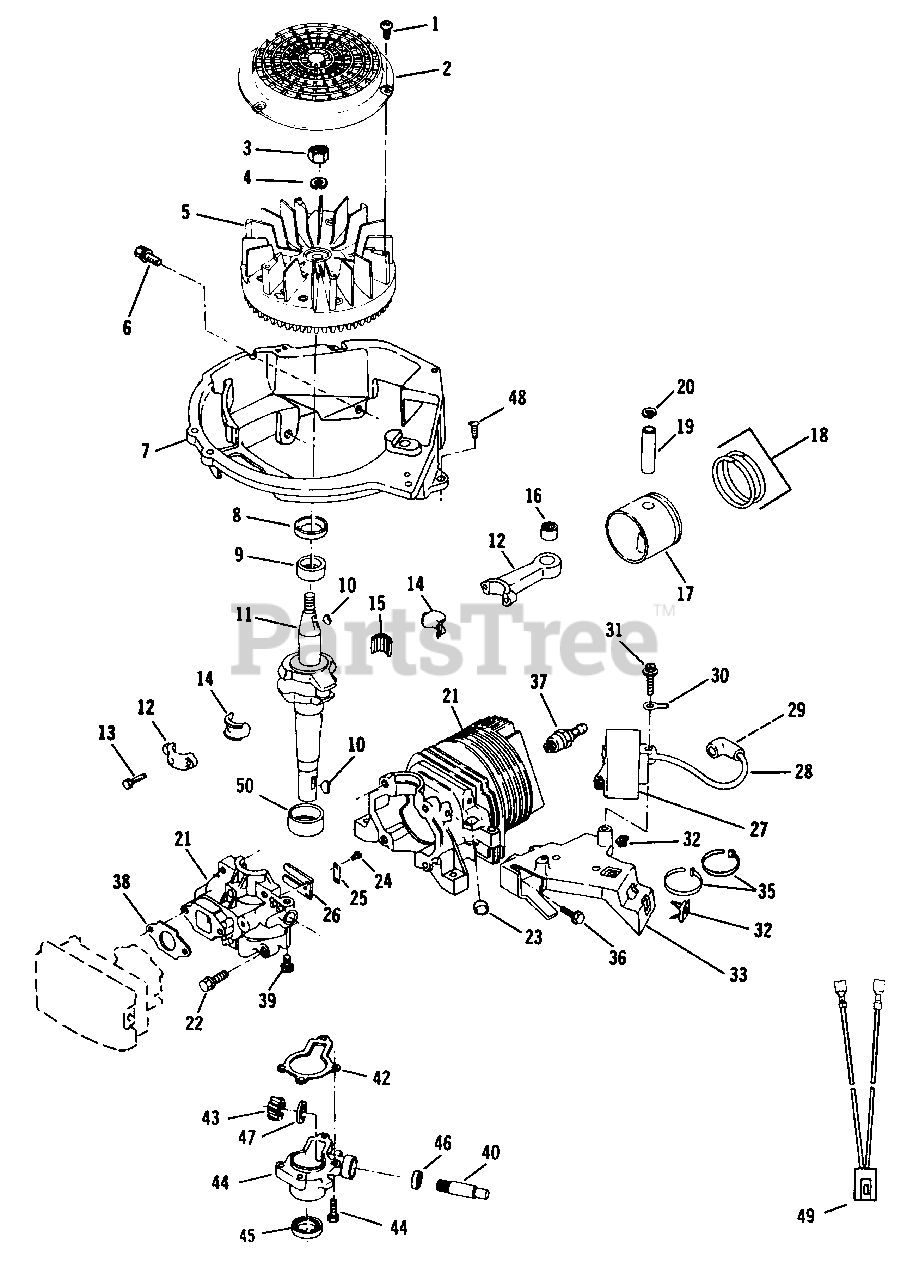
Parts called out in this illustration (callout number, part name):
1	Screw-Flywheel Screen
2	Screen-Flywheel
3	Nut-Flywheel
4	Lockwasher
5	Flywheel Assembly
6	Screw
7	Base-Shroud
8	Oil Seal-Upper
9	Bearing-Upper
10	Key-Flywheel
11	Crankshaft
12	Connecting Rod Assembly
13	Screw Lever
14	Liner-Split
15	Needle Bearing Set
16	Bearing Assembly
17	Piston and Ring Set
18	Ring Set
19	Wrist Pin
20	Retaining Ring
21	Cylinder and Crankcase Cover Assembly
22	Screw-Cover to Crankcase
23	Plug
24	Screw-Reed to C'case Cover
25	Plate-Reed Hold Down
26	Reed
27	C.D. Ignition Module ard Lead Assembly
28	High Tension Lead and Cover Assembly
29	Spring Terminal
30	Terminal-Ground Lead
31	Screw-C.D. Mounting
32	Grommet-C.D. Bracket
33	Bracket-Ignition Mtg.
35	Tie Strap
36	Screw
37	Spark Plug
38	Gasket-Carb. to Crankcase Cover
39	Set Screw-Starter Assembly
40	Driveshaft
41	Screw-Gear Box
42	Gasket-Gear Box
43	Gear
44	Gear Box Assembly
45	Oil Seal-Crankshaft
46	Seal-Driveshaft
47	Washer-Thrust
48	Screw-Shd. Base to C.D. Brk't.
49	Wire Harness-Engine
50	Bearine-Lower
